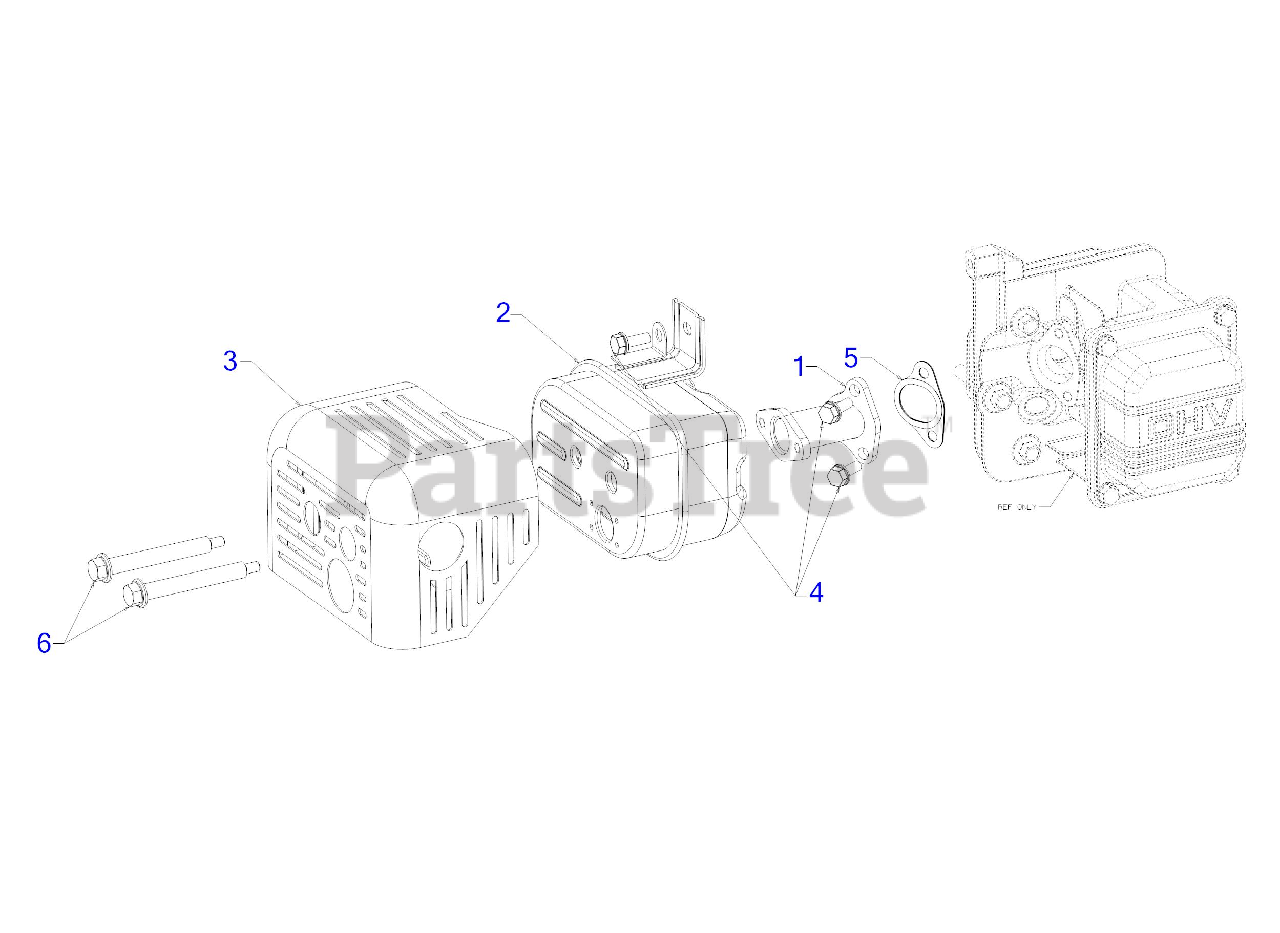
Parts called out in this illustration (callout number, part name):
1	EXHAUST TUBE ASSEMBLY
2	MUFFLER ASSEMBLY
3	COVER-MUFFLER A
4	BOLT M6-1 x 16 GR8.8
5	EXHAUST GASKET
6	SHOULDER SCREW 9.5 x 69 M6-1
